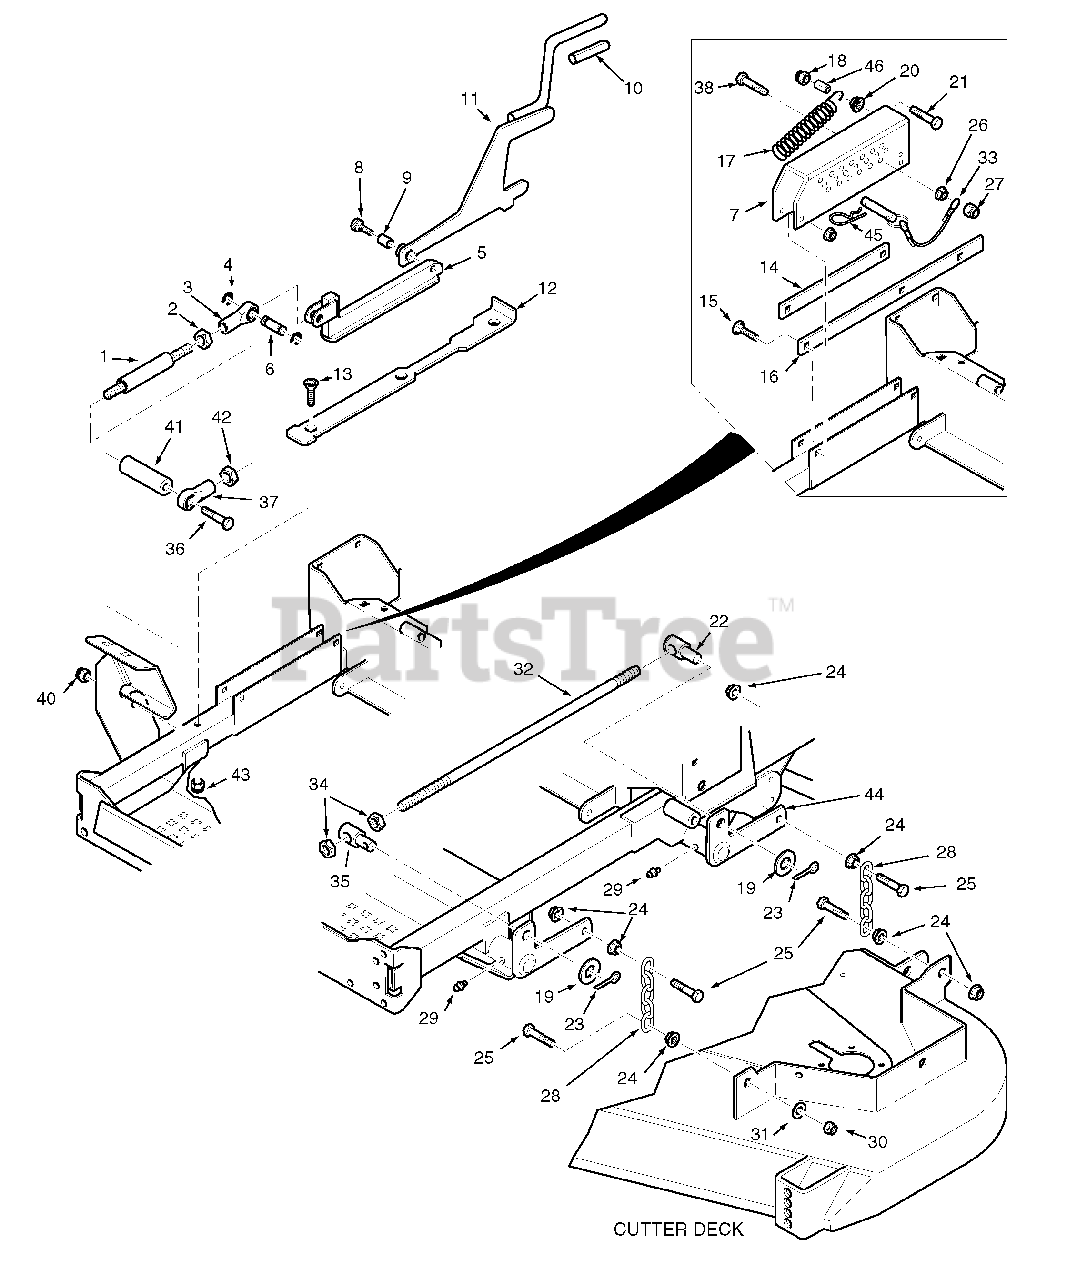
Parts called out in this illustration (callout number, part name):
1	Rod, Deck Lift Linkage
2	Nut, Jam 1/2-20 LH Thread
3	Rod End, 1/2-20 Female Thread
4	Retaining Ring, 1/2" External "E"
5	Slide, Deck Height Adjust
6	Pin, Deck Lift
7	Bracket, Cutting Height Adjustment
8	Bolt, Shoulder 1/2-3/4"
9	Bushing .502 ID
10	Grip, Deck Latch Lever
11	Lever, Deck Latch
12	Slide, Cutting Height
13	Screw, Cap 5/16-18 x 3" FHHS
14	Guide, Short
15	Bolt, Carriage 5/16-18 x 1"
16	Guide, Long
17	Spring, Helper
18	Nut, 3/8-16 Center Lock
19	Flatwasher, 5/8-.656 x 1.312 x .095
20	Nut, 3/8-16 Serr. Flange
21	Bolt, Hex Head 3/8-16 x 1-1/4"
22	Swivel Joint LH
23	Cotter Pin, 3/16 x 1"
24	Nut, Serr. Flange 3/8-16
25	Bolt, Hex Head 3/8-16 x 1-1/2"
26	Nut, Serr. Flange 3/8-16
27	Nut, Elastic Stop 3/8-16
28	Chain
29	Grease Fitting, 1/4-28 Self Tap
30	Nut, Elastic Stop 3/8-16
31	Flatwasher, 3/8-.391 x .938 x .105
32	Stud, 1/2-13 x 20"
33	Lanyard Pin
34	Nut, 5/8-11 UNC
35	Swivel Joint RH
36	Bolt, Hex Head 1/2-13 x 5"
37	Rod End, 1/2-20 Female RH Thread
38	Bolt, Hex Head 3/8-16 x 3-1/2"
39	Spacer
40	Lock Nut, 1/4-20
41	Spacer
42	Nut, 1/2-20 UNF-2B
43	Nut, Elastic Stop 5/16-18
44	Lift Bellcrank Weldment, LH Rear
44	Lift Bellcrank Weldment, RH Rear
44	Flatwasher, 1.0-1.062 x 1.5 x .048
44	Retaining Ring, 1" ext.
45	Hair Pin Cotter, .177 x 3-1/4"
